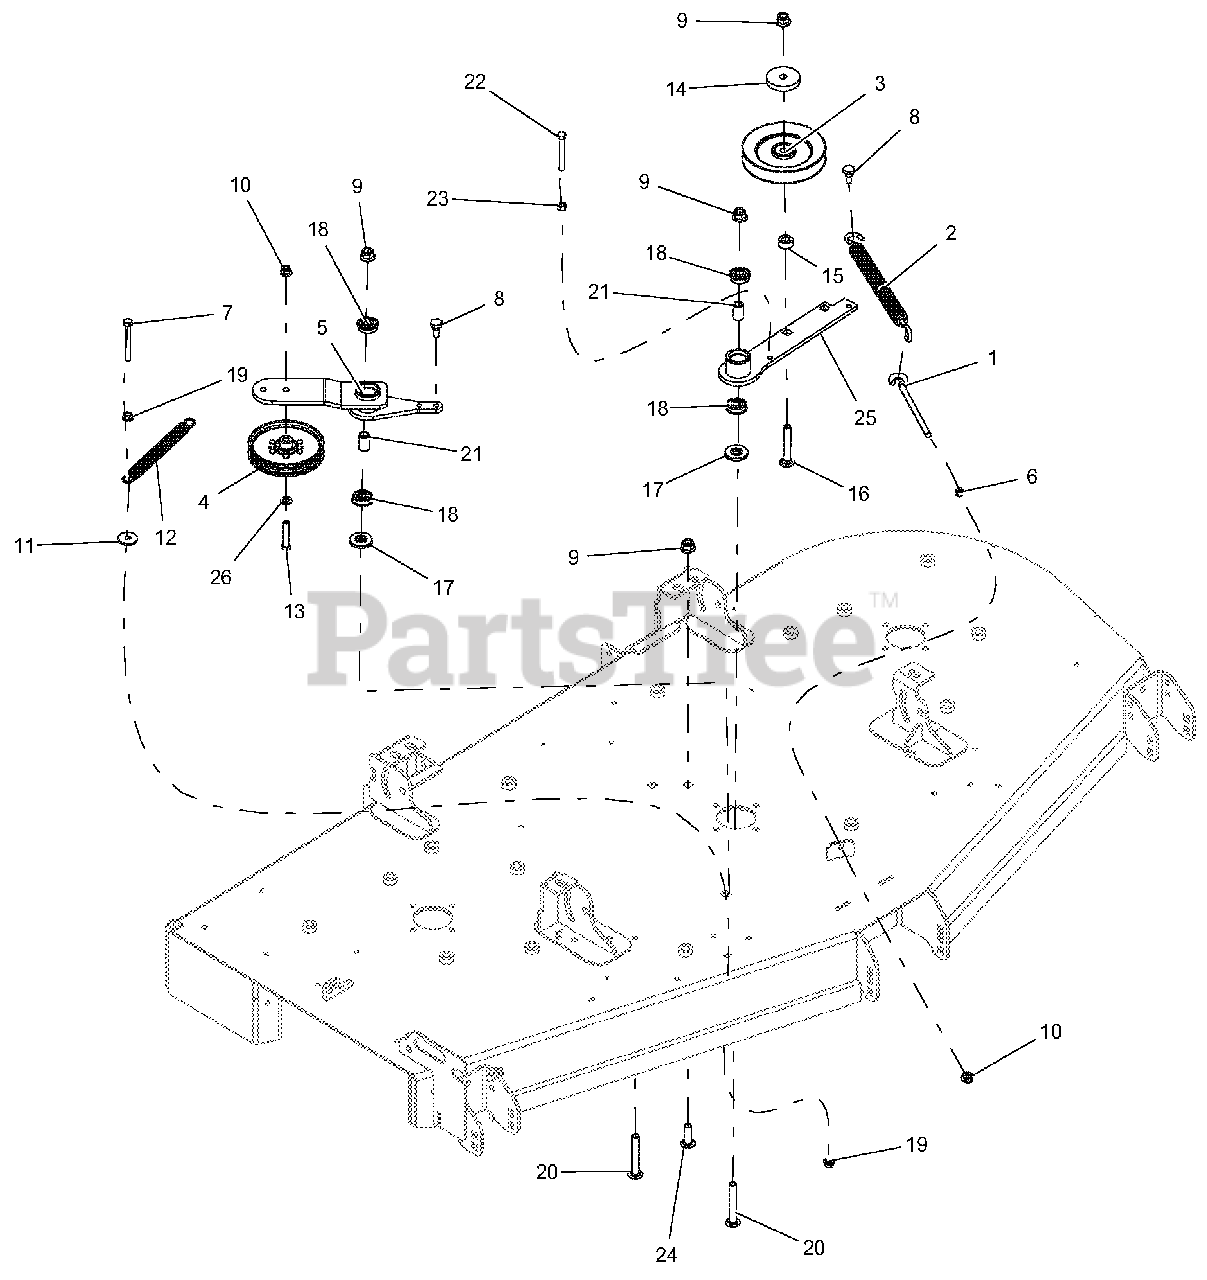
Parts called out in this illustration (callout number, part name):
1	BOLT, .38-16X6.00 .62 DIA EYE
2	SPRG, EXTENSION
3	SHEAVE, .50" ID X 6.00" OD V-IDLER
4	PULLEY, FLAT IDLER .500 X .375 W/BRG
5	WLDMT, DECK RH IDLER ARM
6	NUT, JAM .375-16 YWZC
7	BLT-HEX .38-16X3.00 GR5 YWZC
8	BLT, SHLDR EP .38-16X.30 HEX YZ
9	NUT-LK-NYL-FLG .50-13 YWZC
10	NUT-LK-NYL-FLG .38-16 YWZC
11	WSHR-FL-STL .406X1.375X.135 YZ
12	SPRG, EXTENSION .120X.845X6.55 WLD
13	BLT-HEX .38-16X2.00 GR5 YWZC
14	CAP, IDLER BEARING SEALING
15	BSHG, SPCR .502 X .997.50 PM
16	BLT-RDHDSQNK .50-13X3.00 G5 Y
17	SPACER, IDLER ARM
18	BRG, BALL .501 X 1.38 X .438 SEALED
19	@NUT-SPNLK-FLG .375-16 YWZC
20	BLT-RDHDSQSHNK .50-13X3.25 YWZC
21	SPACER, .510 X .750 X 1.148
22	BLT-HEX .38-16X2.75 GR5 YWZC
23	NUT-HEX .38-16 YWZC
24	BLT-RDHDSQSHNK .50-13X1.50 YWZC
25	WLDMT, DECK PTO IDLER ARM-BLACK
26	WSHR-FL-STL.406X.812X.065 YWZ
